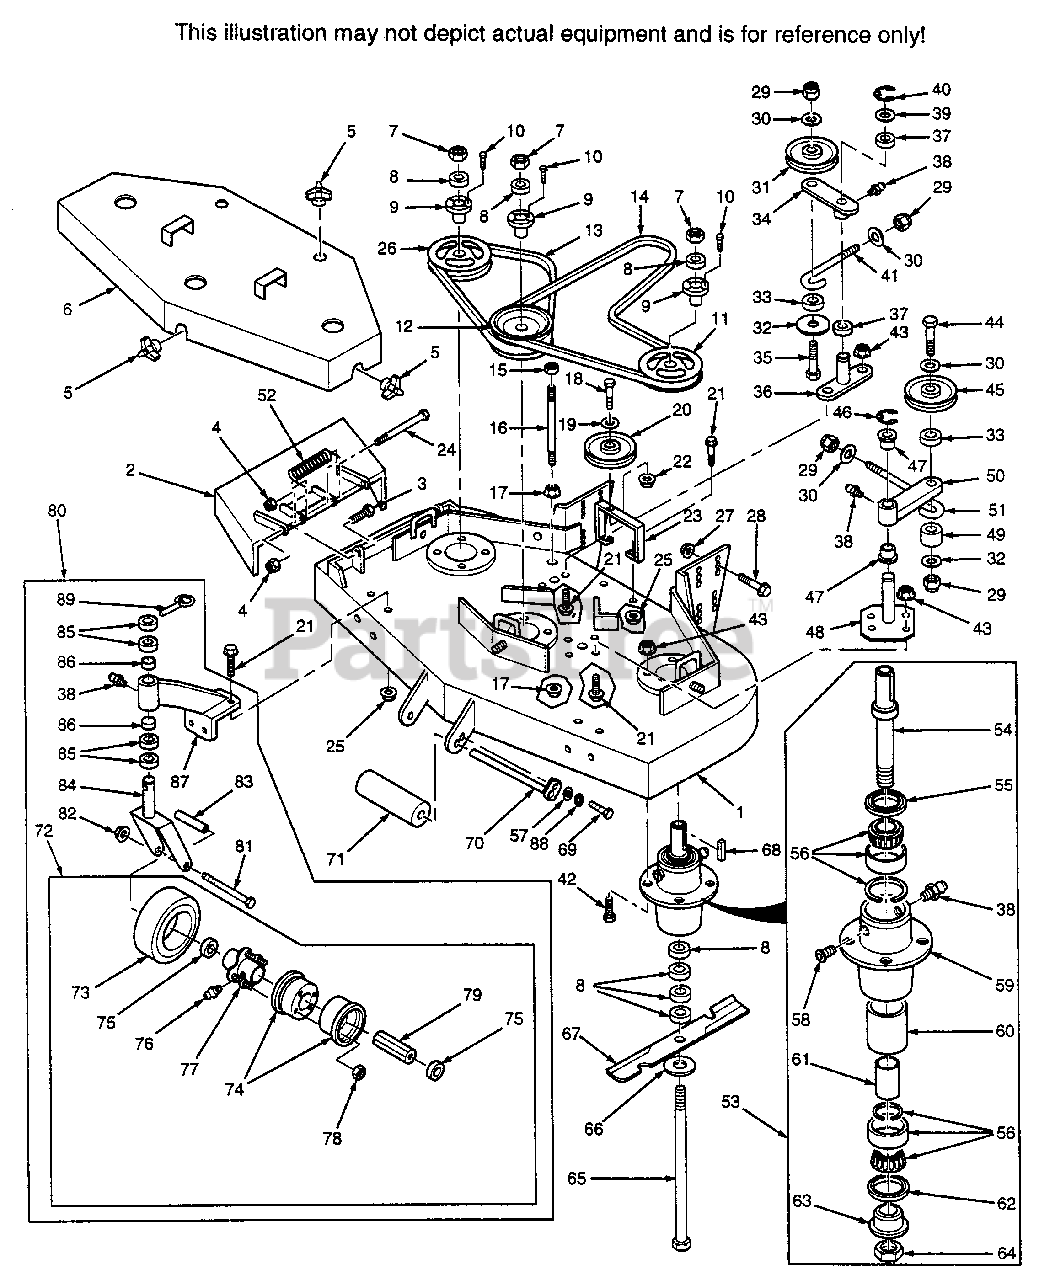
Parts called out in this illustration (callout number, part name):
1	CUTTER DECK(INCLUDES DECALS)
2	DISCHARGE CHUTE
3	BOLT, 5/16-18 X 1" HEX HEAD
4	NUT, 5/16-18 ELASTIC STOP
5	WING NUT, 3/8-16 X 7/8
6	BELT COVER(INCL. DECALS)
7	NUT, 5/8-11 HEX HEAD
8	SPACER, CUTTER BLADE
9	TAPERED HUB, 1.125 BORE
10	BOLT, 1/4-20 X 3/4 HEX HEAD
11	PULLEY, 5.75 O.D.
12	PULLEY, DOUBLE GROOVE, 5.75 O.D.
13	BELT, R.H. BLADE DRIVE
14	BELT, DECK DRIVE
15	LOCK NUT, 3/8-16 HEX HEAD
16	STUD, 3/8-16 X 6-3/4"
17	NUT, 3/8-16 SERR. FLANGE
24	BOLT, 5/16-18 X 1-1/4"
25	NUT, 5/16-18 SER. FLG. HEX HD.
26	PULLEY, 5.75
27	NUT, 1/2-13 SER. FLG. HEX HD.
28	CAPSCREW, 1/2-13 X 1-1/4 SER. FLG.
29	NUT, 3/8-16 ELASTIC STOP
30	FLATWASHER, 3/8(.391 X .938 X .105)
31	PULLEY
32	FLATWASHER, 3/8(.375 X 1.50 X .060)
33	SPACER
34	IDLER ARM(INCL. 37 & 38)
36	IDLER PIVOT
37	BEARING, BRONZE OILITE
38	GREASE FITTING, STR. 1/4-28 SELF TAP.
39	FLATWASHER, 1-1/4 X .059 THICK
39	FLATWASHER, 1-1/4 X .035 THICK
40	RETAINING RING
41	J-ROD IDLER PULLEY
42	BOLT, 5/16-18 X 1-1/4"
43	NUT, 5/16-18 SER. FLANGE
44	BOLT, 3/8-16 X 3-1/2" HEX HEAD
45	PULLEY, DECK DRIVE IDLER
46	RETAINING RING
47	BEARING, BRONZE OILITE
48	IDLER PIVOT SUPPORT
49	SPACER
50	IDLER ARM(INCL. 38 & 47)
51	J-ROD, DRIVE IDLER
52	SPRING, CHUTE RETURN
53	SPINDLE ASSEMBLY
54	SHAFT, CUTTER SPINDLE
55	SEAL, 2.00 O.D. X 1.50 BORE
56	BEARING ASSEMBLY
57	FLAT WASHER, 5/16
58	RELIEF FITTING, CUTTER SPINDLE
59	SPINDLE HOUSING
60	SPACER, OUTSIDE
61	SPACER, INSIDE
62	SEAL, 2.00 O.D. X 1-5/8 BORE
63	SPINDLE BUSHING BOTTOM
64	NUT, 1-1/16-18 UNEF-2B
65	BOLT, 5/8-11 X 9-1/2"
66	FLATWASHER, 5/8
67	CUTTER BLADE, 18" STANDARD
67	CUTTER BLADE, 18" HI-LIFT
68	KEY, 1/4 X 1/4 X 2"
69	BOLT, 5/16-18 X 3/4" HEX HEAD
70	SHAFT, ROLLER
71	GUIDE, ROLLER
72	WHEEL ASSY., CASTER
73	TIRE ONLY, CASTER WHEEL
73	INNER TUBE ONLY, CASTER WHEEL
74	RIM PAIR, CASTER WHEEL
75	RETAINER, CASTER WHEEL
76	GREASE FITTING, 45 DEG. 1/4-28
77	HUB ASSY. W/BOLTS, CASTER WHEEL
78	TAPERED HEX NUT, 5/16-18
79	ROLLER BEARING, CASTER WHEEL
80	CASTER WHEEL ASSEMBLY
81	BOLT, 1/2-13 X 5-1/2" HEX HEAD
82	NUT, 1/2-13 ELASTIC STOP
83	SLEEVE, CASTER WHEEL BEARING
84	CASTER YOKE
85	SPACER, CASTER YOKE 1/2"
86	BUSHING, 5/8 X 1" FLANGED
87	SUPPORT ASSEMBLY(INCL. 88-90)
88	LOCK WASHER, 5/16
89	QUICK PIN
90	PULLEY, 5.75
